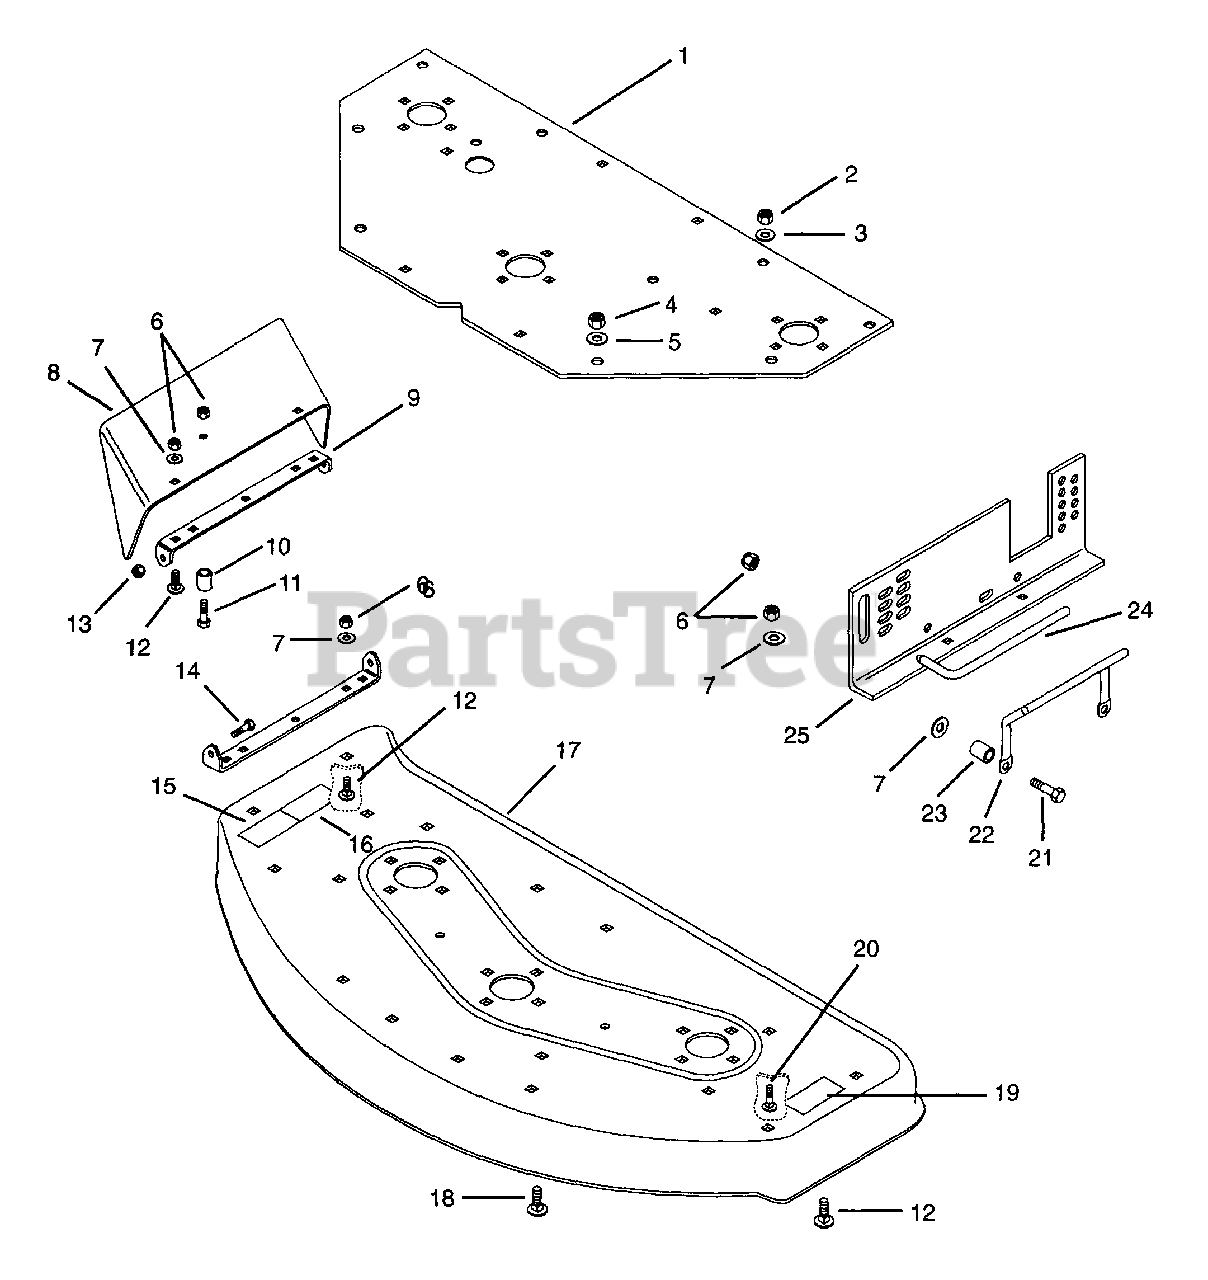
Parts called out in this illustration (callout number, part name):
1	Plate, Support
2	Nut-Locking-Nylon .312-18 Grade 2
3	Washer-Flat-Steel .328 x 1.0 x .094
4	Nut-Locking-Nylon .50-13 Grade 5
5	Washer-Flat-Steel .531 x 1.250 x .100
6	Nut-Locking-Nylon .375-16 Grade 2
7	Washer-Flat-Steel .406 x .812 x .065
8	Chute, 40" Flip-Up
9	Bracket, Chute 40" Mower
10	Bushing-Sleeve .407 x .625 x .750
11	Bolt-Hex .38-16 x 1.50 Grade 5
12	Bolt-Round Head Square Neck .38-16 x 1.0
13	Nut-Locking-Nylon .250-20 Grade 2
14	Bolt-Hex .25-20 x .875
15	Decal, Warning Eye
16	Decal, Danger Hand
17	Weldment, 40" Deck 3-Spindle
18	Bolt-Round Head Square Neck .50-13 x 1.00
19	Decal, Danger Foot
20	Bolt-Round Head Square Neck .31-18 x .75
21	Bolt-Hex .38-16 x 1.75 Grade 5
22	Handle
23	Bushing
24	Pin, Mower Locking
25	Bracket, Mower Side Support (Left Hand)
25	Bracket, Mower Side Support (Right Hand)
